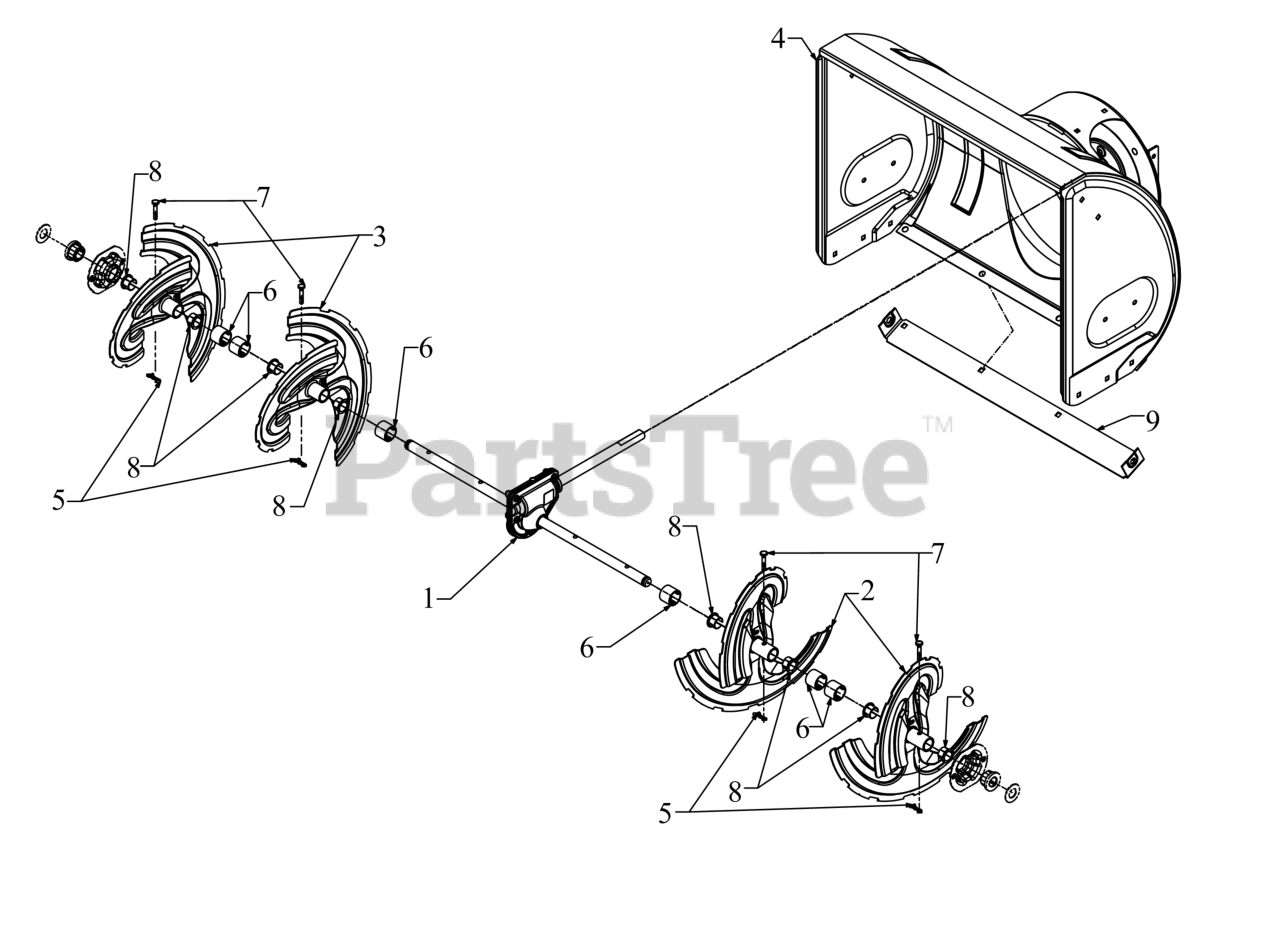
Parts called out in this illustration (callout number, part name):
1	26" GEARBOX ASSEMBLY
2	10T AUGER SPIRAL (LH)
3	10T AUGER SPIRAL (RH)
5	BOW TIE COTTER PIN 1/4-5/16
6	SPACER 1.25OD x .75ID X1.00 LG
7	SHEAR PIN .25 x 1.50 GR2
7	Cub Cadet SHEAR PINS (2X SNOW)
7	SHEAR PINS QTY 4
8	FLANGE BUSHING
